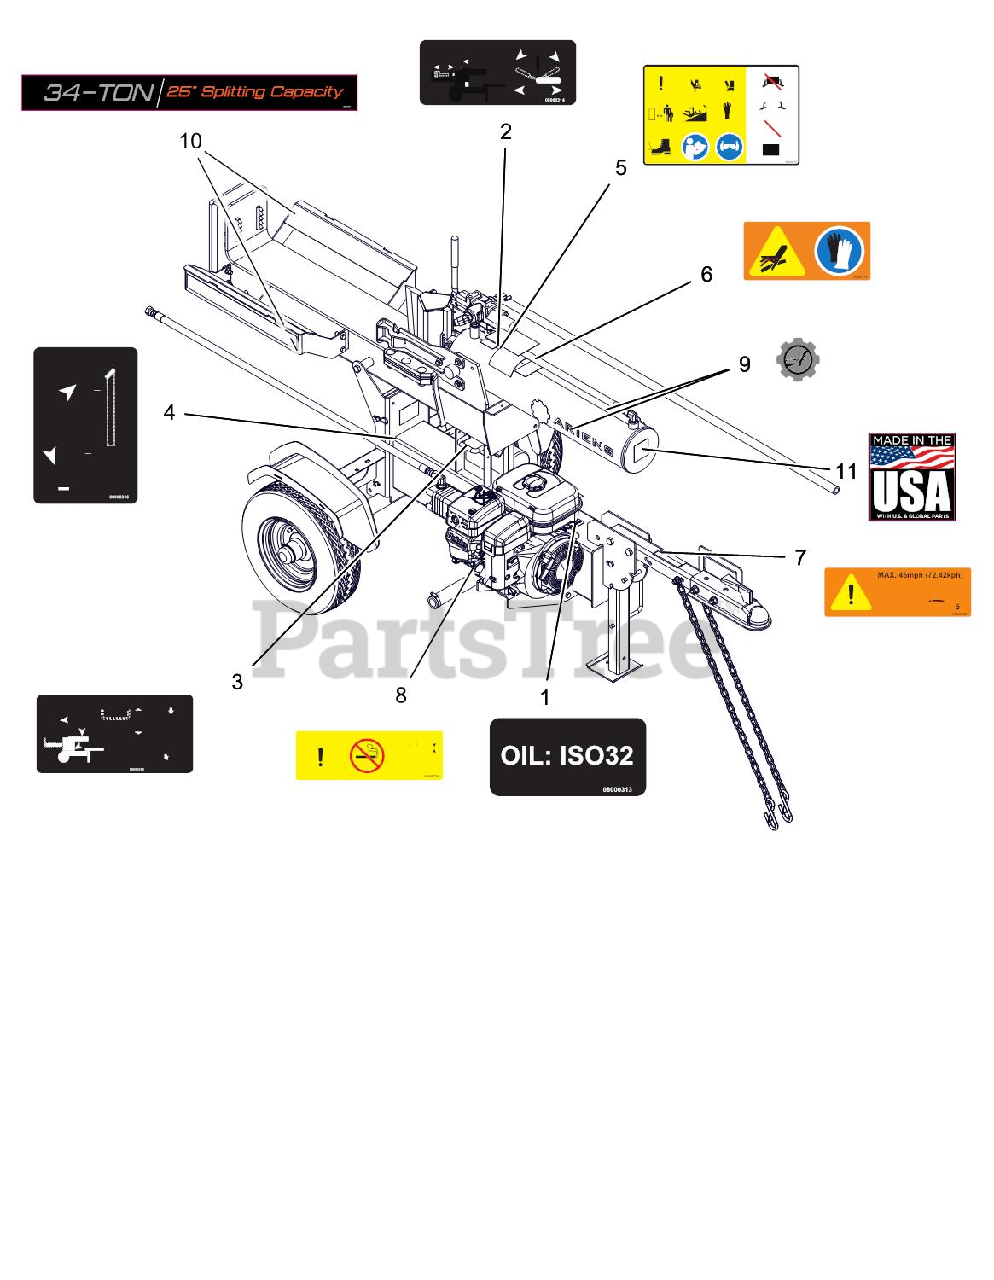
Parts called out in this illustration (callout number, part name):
1	DECAL, LOG SPLITTER-HYD OIL
2	DECAL, LOG SPLITTER-RAM OP
3	DECAL, LOG SPLITTER-TILT OP
4	DECAL, LOG SPLITTER-REAR STAND
5	DECAL,DANGER LOG SPLITTER
6	DECAL,HYD WARNING
7	DECAL,TOWING
8	DECAL,FUEL WARNING
9	DECAL-ARIENS-CYLINDER
10	DECAL-CRADLE-34 TON
11	DECAL, MADE IN USA
